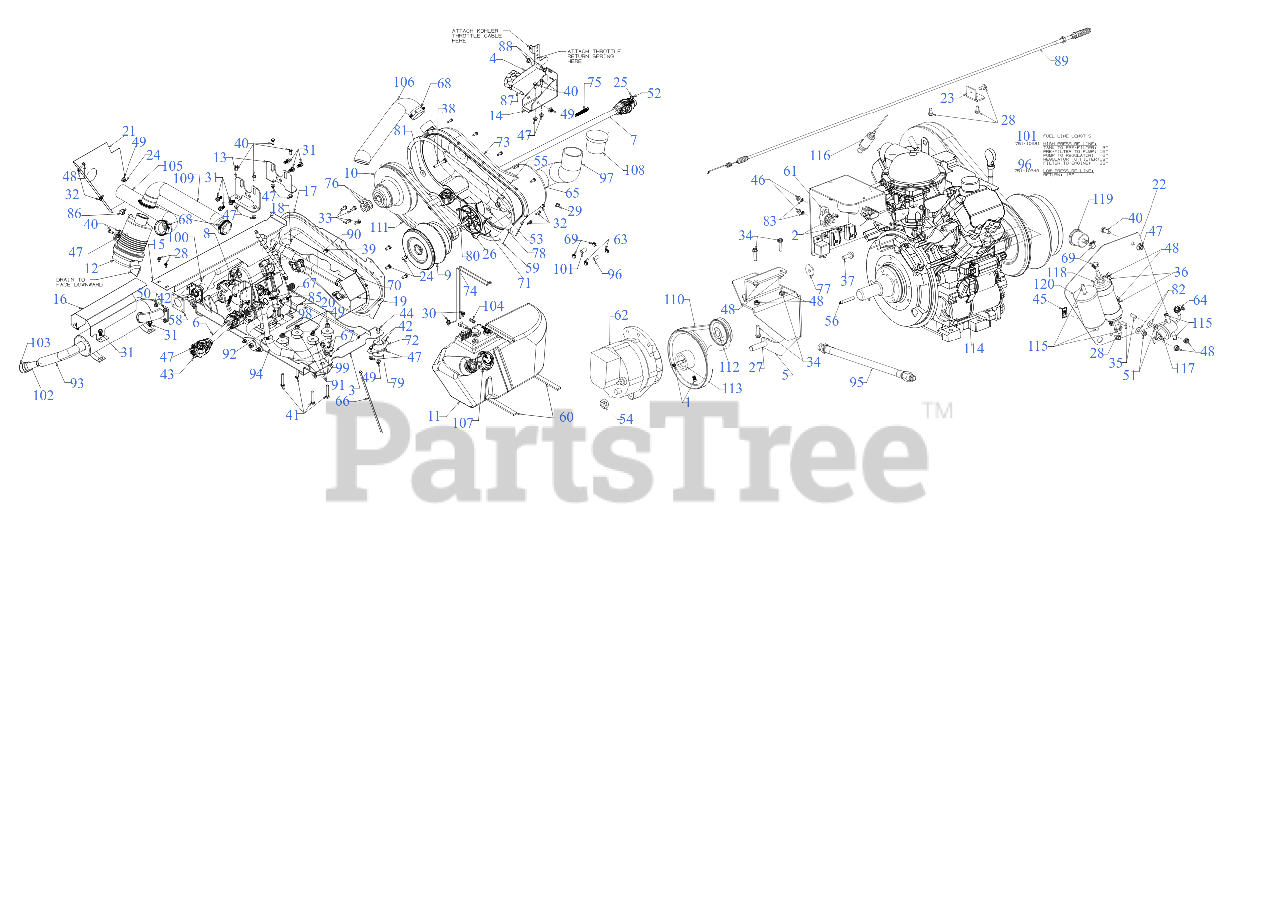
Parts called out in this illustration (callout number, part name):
1	SCREW-SET SQ 1/4-20
2	SCREW:10-32X.562:#8P
3	ENGINE TRAY ASSEMBLY (POWDER BLACK)
5	ALTERNATOR SUPPORT ASSEMBLY (POWDER BLACK)
6	SHAFT ASSEMBLY:RR/PROP
7	SHAFT ASSEMBLY:FRT/PROP
8	TRANSFER CASE KIT
9	CVT DRIVER CLUTCH ASSEMBLY
9	CVT DRIVER SHOULDER SPACER
10	25MM PILOT CLUTCH ASSEMBLY
11	FUEL TANK ASSEMBLY EFI LO-PERM
12	AIR CLEANER FILTER ASSEMBLY
12	AIR FILTER (CAT/DIESEL)
12	DUST VALVE
15	HEAT SHIELD COVER
16	HEAT SHIELD
18	ENGINE COVER
19	ENGINE COVER
20	HARNESS SHIELD
22	FUEL SYSTEM MOUNTING BRACKET(POWDER BLACK)
24	HEX SCREW 3/8-16 x .75
25	SCREW 5/16-18 x 1.875 GR5
26	SCREW 7/16-20 x 5.00 GR5
27	SCREW 1/2-13 x 2 GR5
28	SCREW 1/4-20 X.500
29	SCREW 5/16-12 x 1/2
30	SCREW 5/16-18 x .500
31	SCREW 3/8-16 x 3/4
32	SCREW 1/4-20 x .750
33	SCREW 5/16-18 x .875
34	SCREW 1/4-20 x 1.00
35	SCREW 1/4-20X.75
36	SCREW 1/4-20 x .625
37	SCREW 5/16-18 x .875 GR5
38	SCREW 3/8-24 x 2.50 GR8
39	SCREW 1/4-20 X1.625
40	SCREW 5/16-18 x .75 GR5
41	SCREW 3/8-16 x 2.25 GR5
42	SCREW 5/16-18 x .875 GR5
43	SCREW 5/16-18 x 2.0 GR5
44	SCREW 3/8-16 x 2.0 GR5
45	SPEED NUT
46	HEX NUT 10-32
47	FLANGE LOCK NUT 5/16-18
48	FLANGE LOCK NUT
50	HEX FLANGE NUT
52	HEX NUT LOCK CENTER
53	HEX NUT CASTLE
54	HEX NUT CTR LK 1/2-13
55	COTTER PIN-3/32 DIA x 1.00
56	SQUARE KEY 1/4 x 1.50
58	ENGINE GASKET
59	CVT COVER SEAL
60	FOAM TAPE .75" WIDE x .25" THICK
61	ELECTRIC POWER DISTRIBUTION POST
62	ALTERNATOR
63	HOSE CLAMP 1/20
64	HOSE CLAMP
65	HOSE CLAMP
66	CABLE TIE 18"
67	HOSE CLAMP
68	HOSE CLAMP 2-3"
69	HOSE CLAMP
70	POP RIVET .125#42
72	ENGINE NEOPRENE MOUNT
74	FUEL TANK WIRE
75	EXTENSION SPRING
76	FLAT WASHER
77	FLAT WASHER
78	FLAT WASHER .510X.995
79	FLAT WASHER .380x2.000x.120
80	FLAT WASHER
81	BELL WASHER
82	FLAT WASHER
83	LOCK WASHER #10
85	1/8 NPT COOLANT DRAIN PETCOCK
86	90 DEGREE FITTING
87	SHOULDER SCREW .50 x 2.23 3/8-16
88	NYLINER BEARING
89	THROTTLE CABLE
91	ENGINE SPACER
92	RADIATOR TUBE
93	MUFFLER (CAT/KOHLER)
94	RADIATOR HOSE
95	OIL DRAIN HOSE
96	FUEL HOSE LOW PERMEATION 16"
97	CVT INTAKE TUBE
98	RADIATOR HOSE (TOP)
99	RADIATOR HOSE (LOWER)
100	EXHAUST PIPE (KOHLER) (EFI)
101	FUEL HOSE LINE 5/16 ID 70"
102	SCREEN ARRESTOR 1.50" DIA
103	CLAMP ARRESTOR 1.50" DIA
104	FUEL HOSE LO PERMEATION 62"
105	AIR INLET HOSE
106	CVT EXHAUST HOSE
107	FUEL CAP (W/TETHER)
108	CVT INLET FILTER
109	AIR INTAKE HOSE
110	BELT 3/8 x 26.680"
112	ALTERNATOR PULLEY
113	PULLEY-6.0 OD 1.12
114	ENGINE ASSEMBLY(LH)775 UV
114	ELECTRICAL BRACKET
115	FUEL LINE CLAMP
116	SENSOR-OXYGEN EFI
117	REGULATOR ASSEMBLY-FUEL
118	PUMP ASSEMBLY-FUEL EFI
119	IN-LINE FUEL FILTER
120	FUEL FILTER EFI
